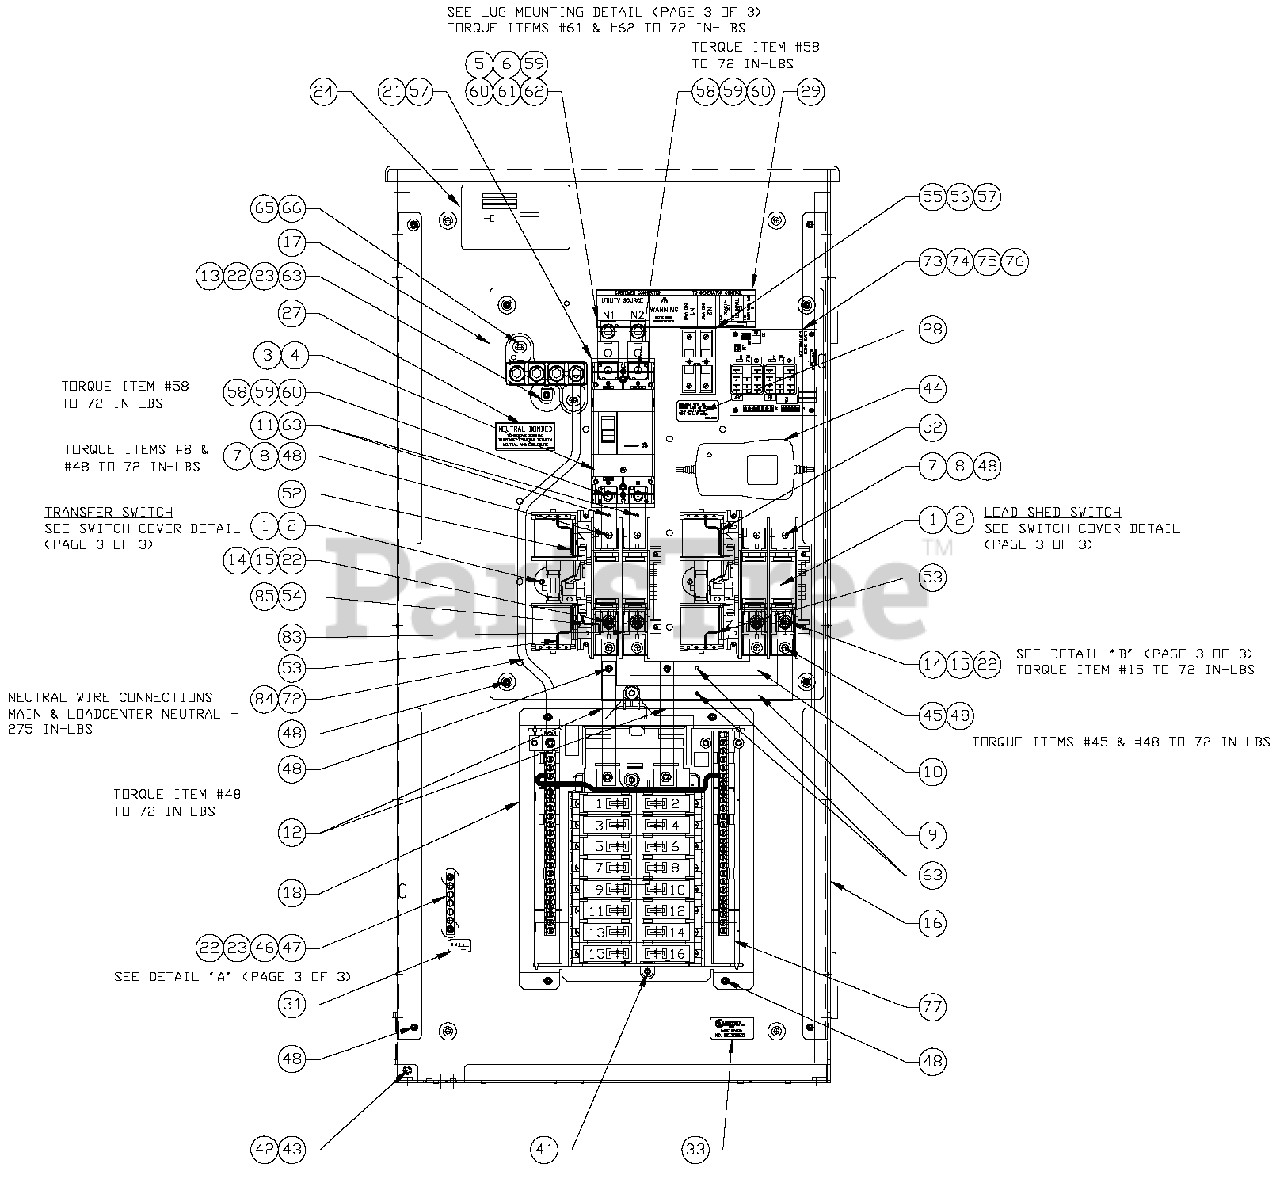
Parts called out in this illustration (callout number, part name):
1	TRANSFER SW. HSB 200A 2P 250V
2	SCREW HHTT M5-0.8 X 10 BP
3	CIRCUIT BREAKER, 200A 2-POLE
4	SCREW RHM #8-32 X 3-1/4
5	BUSBAR, 200A LUG ADAPTER
6	LUG 300 MCM-6STR
7	SPACER 200 AMP TRANSFER
8	BOLT CARR 1/4-20 X 1"
9	BUSBAR, 200A TRANSFER SW T1
10	BUSBAR, 200A TRANSFER SW T2
11	BUSBAR, 200A TRANSFER SW N1,N2
12	BUSBAR, PANELBOARD INTERCONNECTION
13	BUSBAR, NEUTRAL BLOCK
14	LUG SOLDERLESS 250-#6 AL/CU
15	SCREW BHSC 1/4-20 X 3/8
16	ENCLOSURE,LOAD SHED TRANSFER SWITCH
17	SUBPLATE, PANELBOARD
18	SUBPLATE, LOADCENTER
21	CB BRKT 200A TRANSFER SWITCH
22	WASHER LOCK M6-1/4
23	NUT HEX 1/4-20 SS
24	DECAL,LOAD SHED DATA 200A
27	DECAL, NEUTRAL CONNECTION
28	DECAL, FUSE REPLACEMENT
29	DECAL, CUSTOMER CONNECTION
31	DECAL, GROUNDING LUG
33	DECAL-UL PANELBOARD
41	SCREW HHTT M5-0.8 X 16
42	NUT TRIC 1/4-20 X .525
43	THUMB SCREW 1/4-20x1/2
44	BATTERY CHARGER ASSEMBLY
45	SCREW BHSC 1/4-20 X 3/4
46	GROUND BAR (5) 2-14 AWG CONN
47	WASHER SHAKEPROOF EXT 1/4 STL
48	NUT HEX FL WHIZ 1/4-20
54	WIRE E1 3.0"
55	FUSEBLOCK 30A 600V 2 POLE
56	FUSE 5A X BUSS HLDR73591
57	SCREW HHTT M4-0.7 X 10 BP
58	SCREW SHC M8-1.25 X 20 G8
59	WASHER FLAT 5/16-M8 ZINC
60	WASHER LOCK M8-5/16
61	NUT HEX M8-1.25 G8 CLEAR ZINC
62	SCREW HHC M8-1.25 X 25 C8.8
63	SCREW HHTT #8-32 X 1/4 CZ
65	ASSY-NEUT BLK 200-400A W/TAP
66	SCREW HHTT M6-1.0 X 12 MM
72	NEUTRAL WIRE
73	ASSY PCB 2008HSB LOAD SHEDCTRL
74	RELAY SOC 12VDC DPDT 10A@240VA
75	SPACER .20 X .375 X .375 PL
76	NUT HEX FL WHIZ M5-0.8
77	16 CIR L/CENTR 200A/240V SIEMS
83	STRAIGHT SPADE CONNECTOR
84	TIE-WRAP MOUNT(FIR TREE SYTLE)
85	90 DEGREE DN SPADE CONNECTOR
